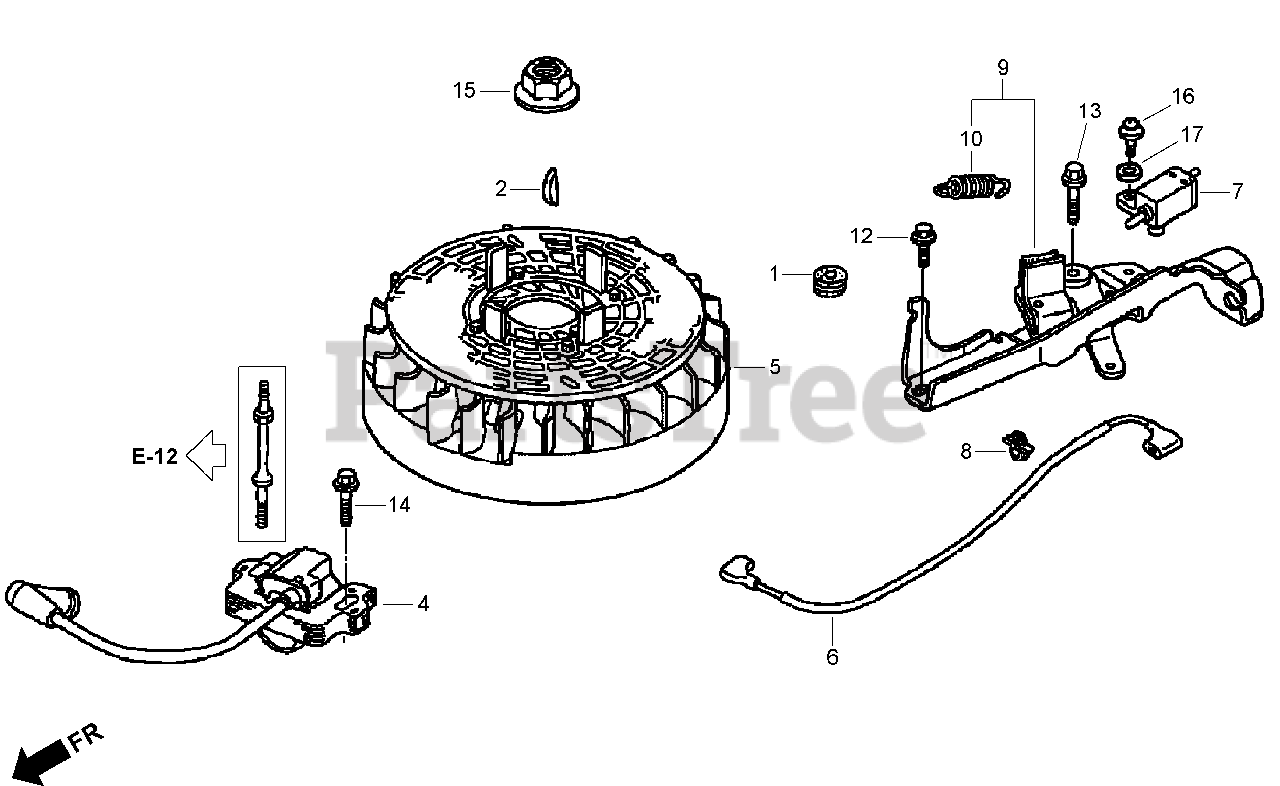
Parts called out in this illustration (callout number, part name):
1	GROMMET A-COVER, R R (8X16X6.6)
2	KEY-WOODRUFF, SPECIAL (25X18)
4	IGNITION COIL ASM (PHELON) (USE FOR FLYWHEEL OF PHELON)
5	FLYWHEEL ASM (PHELON) (USE FOR IGNITION COIL OF PHELON)
6	WIRE-SWITCH, STOP
7	ENGINE STOP SWITCH ASM (N C)
8	HOLDER-WIRE (FASTEX)
8	CLIP A-CABLE (NIFCO)
9	BRAKE ASM
10	SPRING-LEVER, BRAKE
12	BOLT-FLANGE (6X14) (C T200)
13	BOLT-FLANGE (6X23) (C T200)
14	BOLT-FLANGE (6X20) (C T200)
15	NUT-FLANGE (14MM)
16	SCREW-WASHER (4X12)
17	WASHER-PLAIN (4MM)
